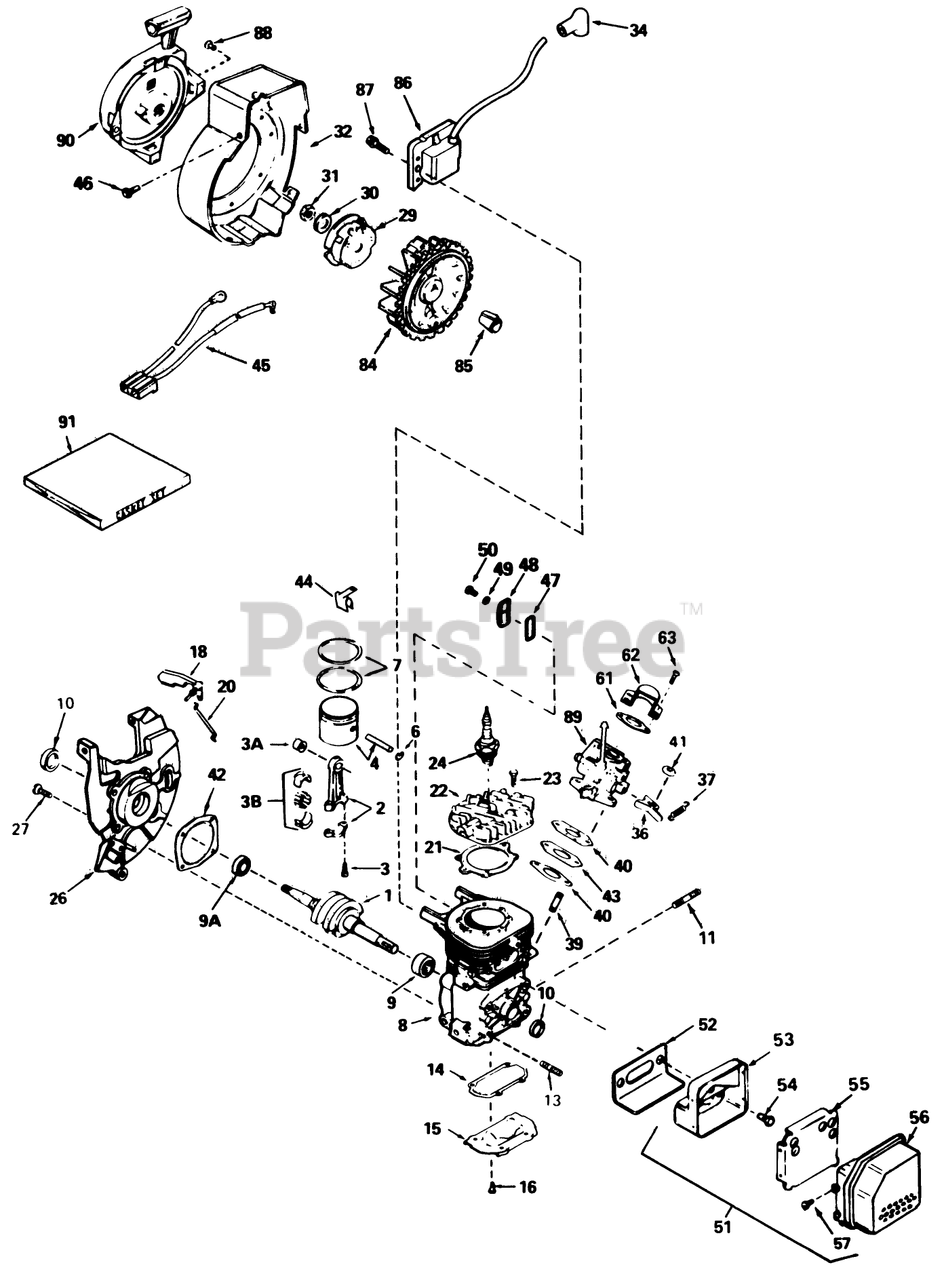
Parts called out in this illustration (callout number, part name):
1	Crankshaft
2	Rod Assy.-Connecting (Incl. Ref. #3, 3A 3B)
3	Bolt-Rod, Connecting
3A	Bearing-Cartridge
3B	Needle Bearing and Liner Set (37 Needles)
4	Piston (Incl. Ref. #43)
6	Ring-Retaning
7	Ring Set
8	Cylinder Block Assembly
9	Bearing-Cartridge
9A	Bearing-Ball
10	Seal-Oil
14	Cover
15	Plate-Cover
16	Screw (T-25, 10-24 x 1/2)
18	Vane-Air
20	Link-Governor
21	Gasket-Head, Cylinder
22	Head-Cylinder
23	Screw (T-30, 1/4-20 x 3/4)
24	Spark Plug-Resistor (R C J 8Y)
26	Blower Housing Base Assy. (Incl. Ref. #10)
27	Screw (T-30, 1/4-20 x 5/8)
29	Cup-Starter
30	Washer-Belleville
31	Nut-Flywheel
32	Housing-Blower
34	Cover-Spark Plug
36	Lever-Adjusting, Rpm
37	Spring-Governor
40	Gasket-Carburetor
41	Nut-Hex.
42	Gasket-Cover, Cylinder
43	Spacer
44	Clip-Wire
45	Harness-Wire
46	Screw-Hex, Hd.
47	Cover-Compression, Release
48	Comp. Release Cover
49	Washer
50	Screw (T-25, 10-24 x 1/2)
51	Muffler Assembly (Incl. Ref. #53-57)
52	Gasket-Exhaust
53	Base-Muffler
54	Screw (T-30, 1/4-20 x 5/8)
55	Baffle-Muffler
56	Cover Muffler
57	Screw
61	Gasket
62	Baffle-Carburetor
63	Screw
84	Flywheel
85	Blade (20 inch)
86	Solid State
87	Screw
88	Rivet-Pop
89	Carburetor (Incl. Ref. #184A)
90	Starter-Rewind
91	Gasket Set
